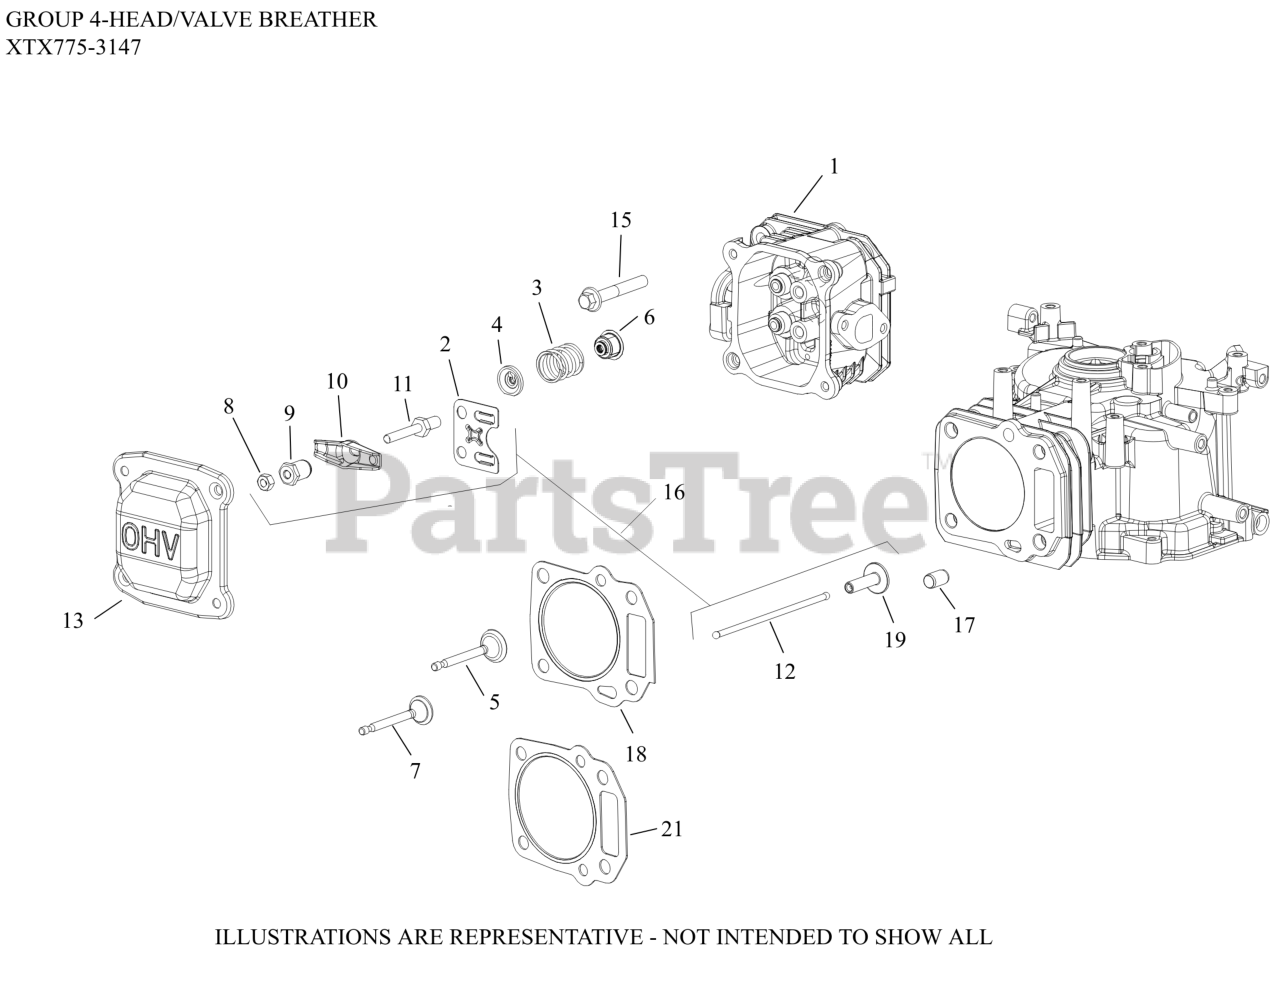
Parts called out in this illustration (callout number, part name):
1	HEAD, CYLINDER
2	PLATE, PUSHROD GUIDE
3	SPRING, VALVE
4	RETAINER, VALVE SPRING
5	VALVE, INTAKE
6	SEAL, VALVE STEM
7	VALVE, EXHAUST
8	NUT, HEX JAM
9	PIVOT, ROCKER ARM
10	ARM, ROCKER
11	STUD, ROCKER ARM
12	ROD, PUSH
13	COVER, VALVE
15	SCREW, HEX FLANGE M8
16	KIT, VALVE TRAIN
17	DOWEL, CYLINDER HEAD
18	KIT, HEAD GASKET-USE 14 841 34-S (XT)
19	LIFTER, VALVE
21	KIT, HEAD GASKET (CV173)
